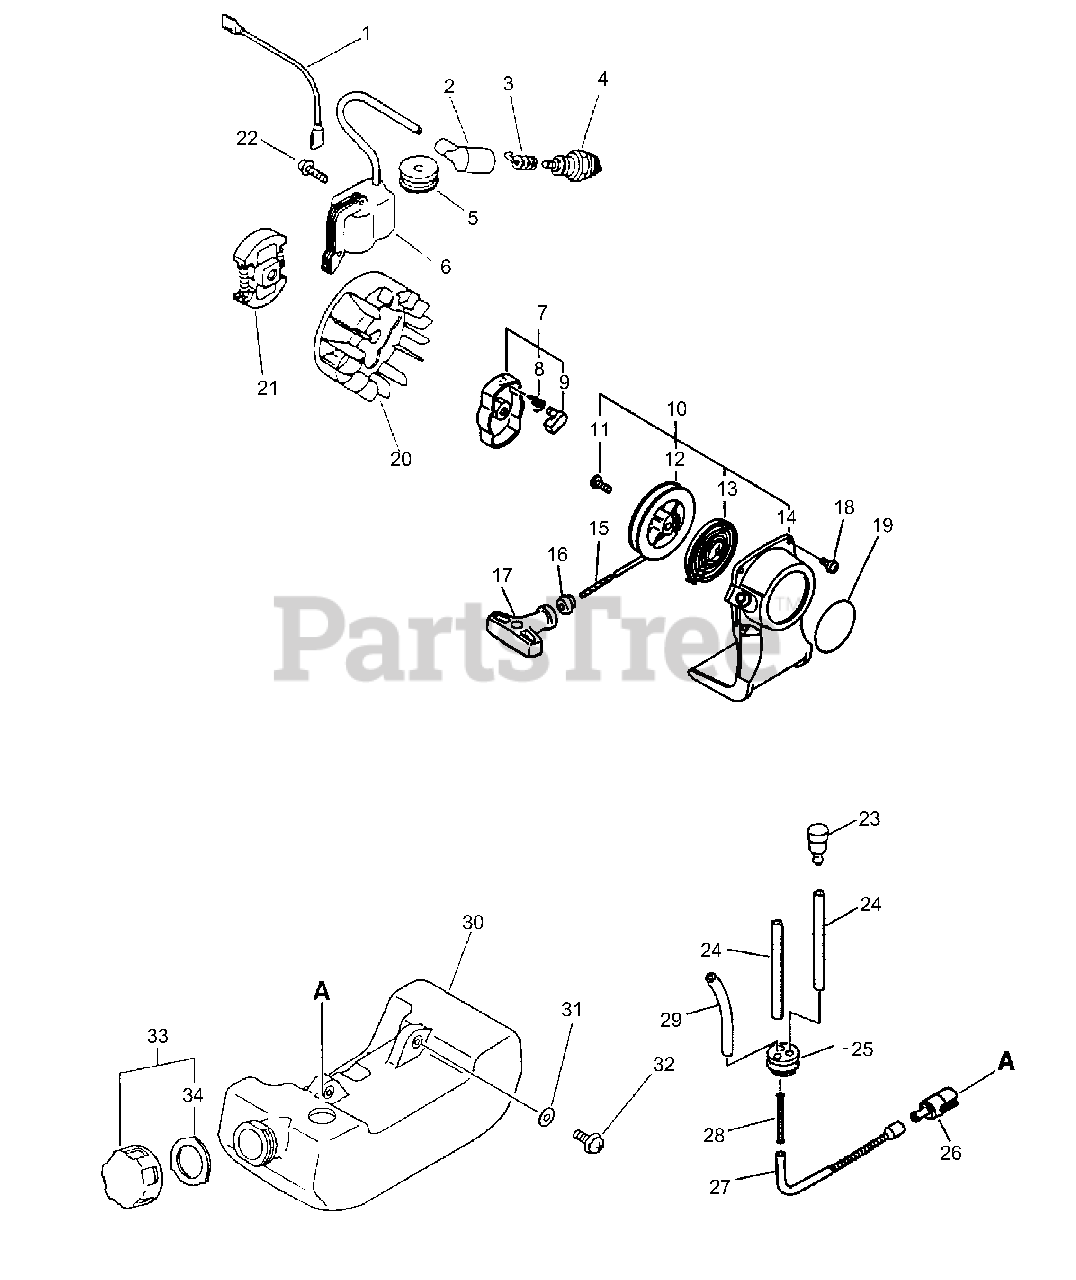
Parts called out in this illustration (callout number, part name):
1	LEAD - IGNITION
2	CAP, SPARK PLUG
3	TERMINAL, SPARK PLUG CAP
4	SPARK PLUG -- BPM-7A
4	SPARK PLUG -- BPMR-7A
5	GROMMET
6	COIL, IGNITION
7	STARTER PAWL ASSY
8	SPRING, RETURN
9	PAWL, STARTER - BLACK
10	STARTER ASSY
12	REEL, ROPE
13	SPRING, REWIND
14	CASE, STARTER - BLUE
15	ROPE, STARTER - 3X890
16	GUIDE, ROPE
17	GRIP, STARTER
18	SCREW - 4X16
19	LABEL - ECHO
20	FLYWHEEL
21	CLUTCH ASSY
22	SCREW - 4X22
23	VENT, FUEL TANK
24	PIPE - 3X5X70 -- BLACK
25	GROMMET
26	FILTER, FUEL
27	PIPE, FUEL - CORRUGATED
28	CONNECTOR, PIPE
29	PIPE - 3X6X90 -- CLEAR
30	FUEL TANK ASSY
31	WASHER - 5
32	SCREW - 5X16
33	CAP ASSY
34	GASKET, CAP
